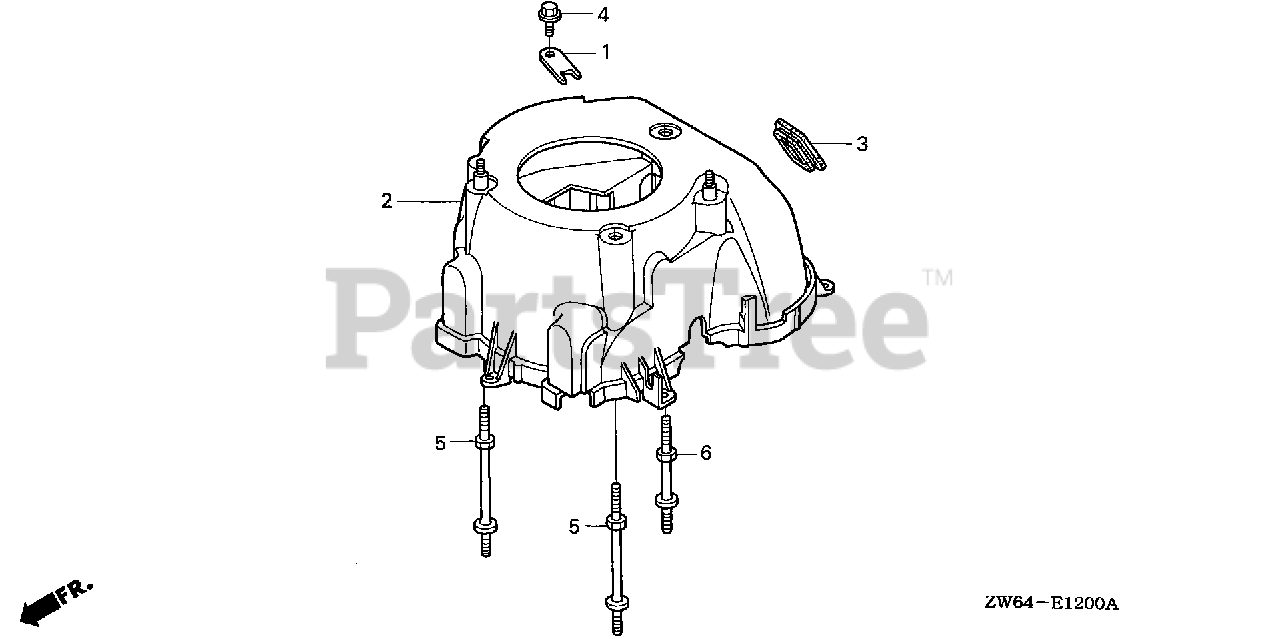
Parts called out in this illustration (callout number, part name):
1	HOLDER, CABLE
2	COVER, FAN
3	GROMMET, FAN COVER
4	BOLT, FLANGE (5X10)
5	BOLT A, STUD
6	BOLT B, STUD
